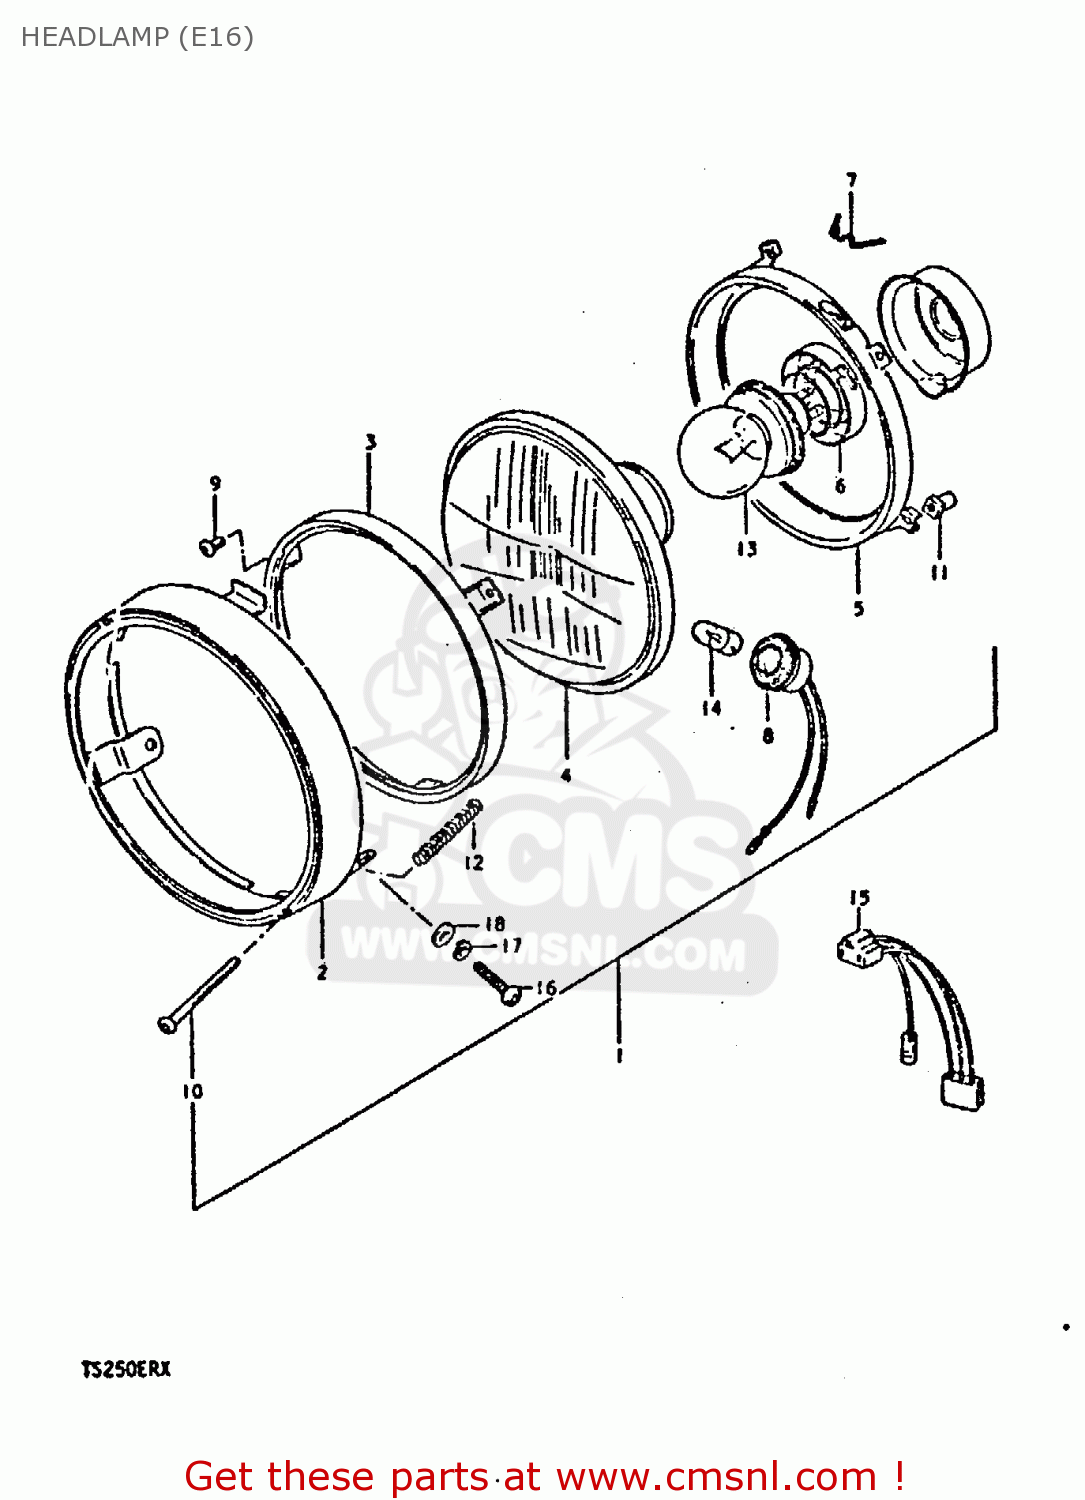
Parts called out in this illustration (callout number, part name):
1	HEADLAMP ASSY
2	RIM
3	RETAINER,HEADLAMP
4	UNIT
5	RING,HEADLAMP UNIT
6	SETTER,BULB
7	SPRING,HEADLAMP UNIT
8	SOCKET
9	SCREW
10	SCREW,HEADLAMP ADJUST
11	NUT,HEADLAMP ADJUSTER
12	SPRING,ADJUSTING
13	BULB (6V,45/40W)
14	BULB(6V4W,STANLEY,A1364J)
15	LEAD WIRE,HEADLAMP
16	SCREW
17	LOCK WASHER
18	WASHER
